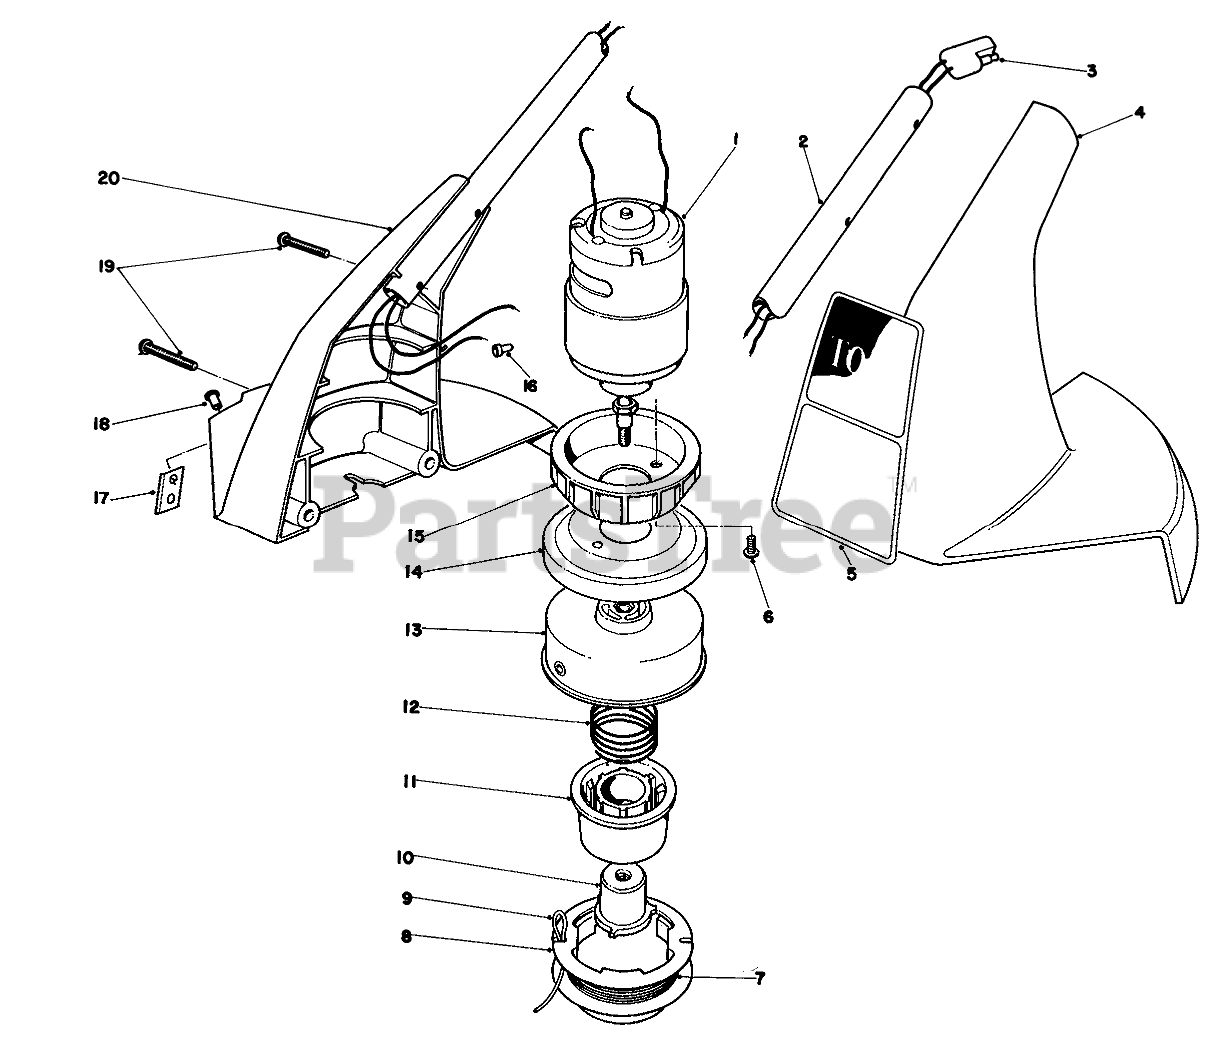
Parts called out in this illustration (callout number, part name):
1	Motor
2	TRIGGER LOCK
3	WIRING HARNESS LOWER
4	Housing-L.H.
5	Decal-Housing
6	Screw
7	Prewound Spool
8	SPOOL CAP
9	.040" Cutting Line in Coil
10	DRIVER
11	CORE - SPOOL
12	Spring
13	Drum w/Eyelet
14	DRUM CUP
15	Casting-Heat Sink
16	Connector
17	Knife Blade
18	Rivet
20	R.H. Motor Housing (Incl. Ref. #17&18)
